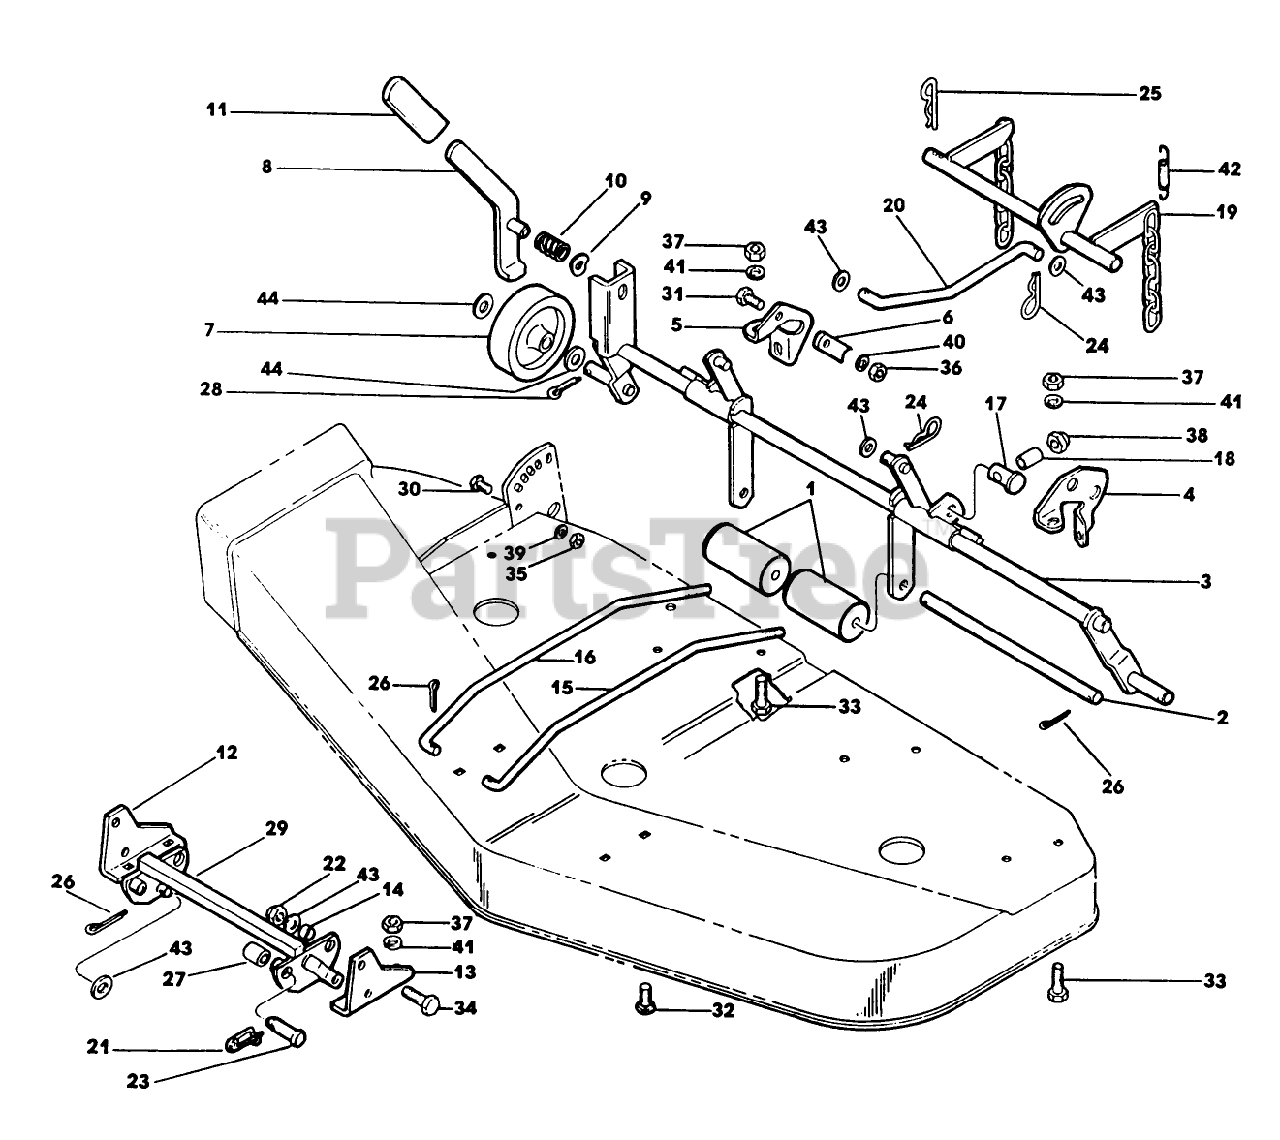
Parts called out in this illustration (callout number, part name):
1	ROLLER
2	SHAFT - ROLLER
7	WHEEL - MOWER
17	PIN - PIVOT
19	BELLCRANK ASSEMBLY *B
20	LINK - MOWER LIFT
21	PIN - SAFETY
22	NUT-LOCKING
23	PIN - CLEVIS
24	PIN-HAIR
27	SPACER
30	SCREW-HH
31	SCREW - HEX
32	BOLT - CARRIAGE
35	NUT
36	NUT SS
37	NUT
38	NUT-HEX CONE LOK
41	WASHER
43	WASHER
